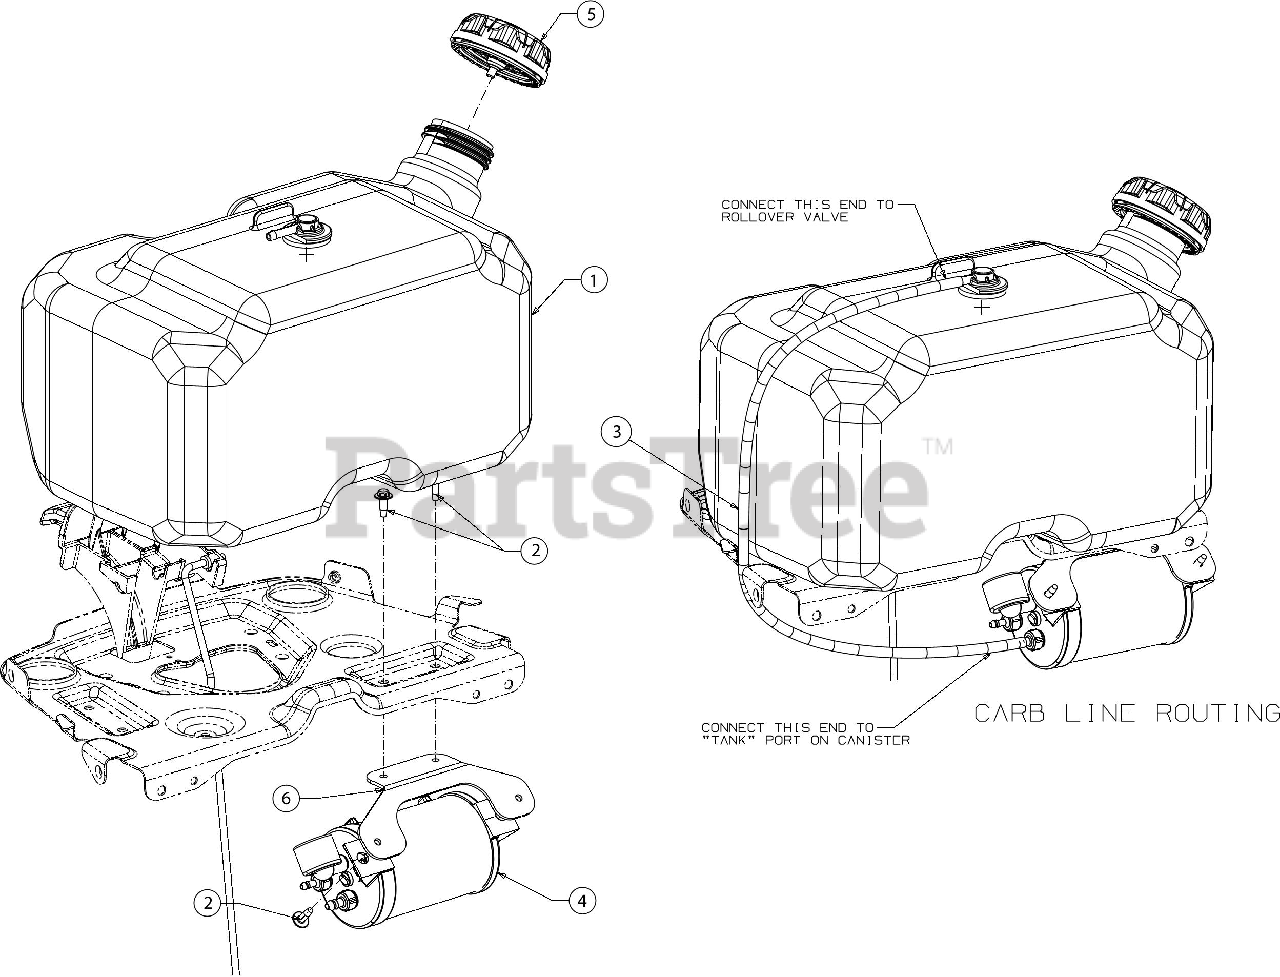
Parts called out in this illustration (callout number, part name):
1	FUEL TANK ASSEMBLY
2	SCREW M6-1 x .625
3	VENT HOSE 3/16 ID
4	CARBON CANISTER
5	FUEL CAP W/TET
